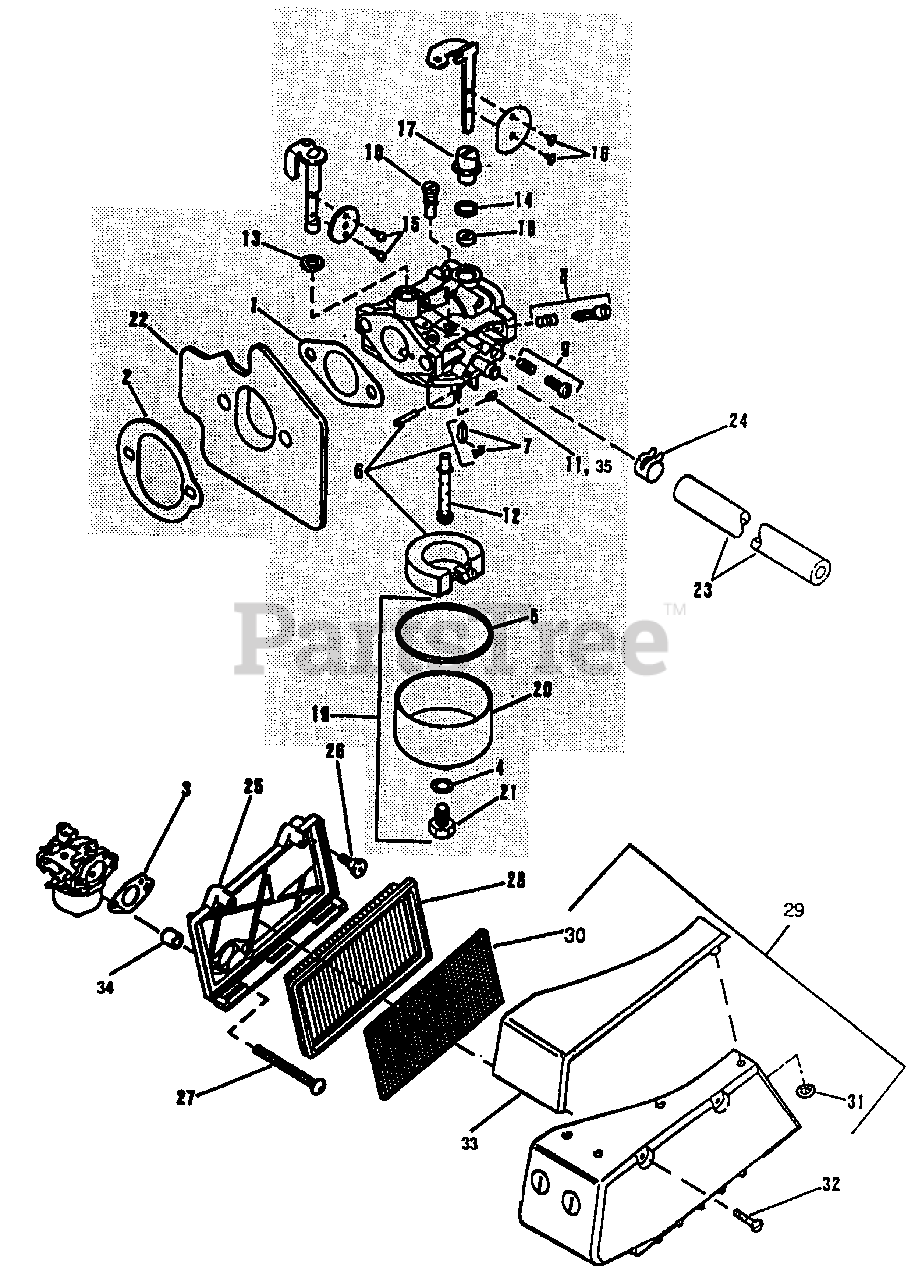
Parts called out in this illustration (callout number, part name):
1	Gasket-Carburetor to Spacer
2	Gasket-Spacer to Engine
3	Gasket-Air Filter Base
4	Gasket-Bowl Retainer
5	Gasket-Fuel Bowl
6	Float and Needle Kit
7	Needle and Clip
8	Idle Needle and Spring Kit
9	Idle Speed Kit
10	Pilot Jet
11	Main Jet
12	Nozzle
13	Throttle Shaft Seal
14	Choke Shaft Seal
15	Screw-Throttle Valve
16	Screw-Choke Valve
17	Upper Choke Shaft Pivot
18	Lower Choke Shaft Pivot
19	Bowl Kit
20	Fuel Bowl
21	Screw-Bowl Retainer
22	Spacer and Oil Nozzle Assembly (BMRB, C & D)
23	Gas Line
24	Hose Clamp
25	Air Filter Base
26	Bolt
27	Screw-Carburetor to Engine
28	Air Filter
29	Air Filter Cover Assembly
30	Pre-Filter
31	Pushnut
32	Screw
33	Air Box Cover
34	Spacer
35	Main Jet-High Altitude
